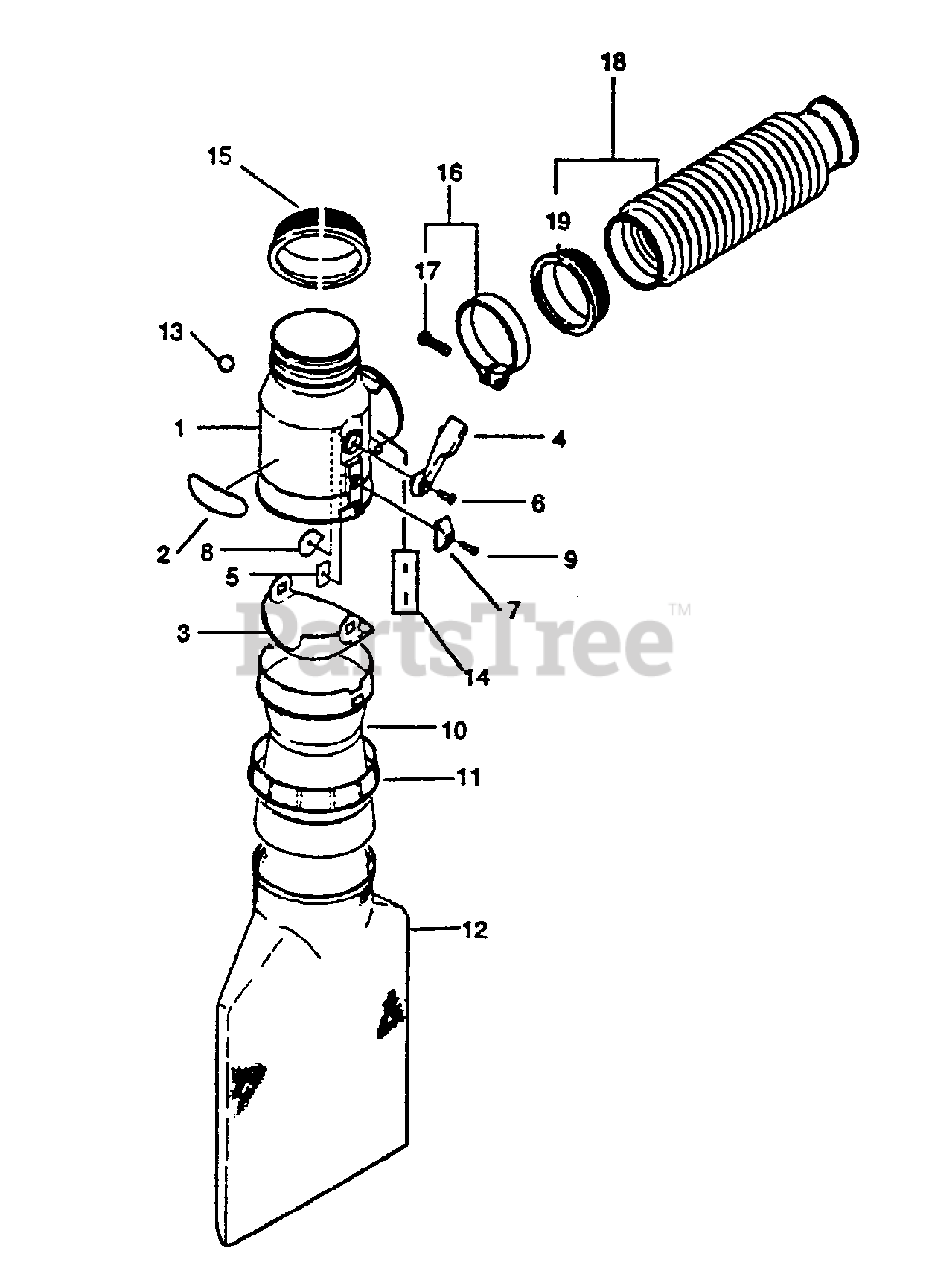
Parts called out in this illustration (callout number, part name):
1	TUBE, SUCTION
2	LABEL - ECHO
6	SCREW - 5X14
9	SCREW - 4X14
10	CONNECTOR
12	BAG, DEBRIS
13	RING, RETAINING - 8
14	LABEL - FUNCTION
15	COUPLER, SUCTION
16	CLAMP KIT
17	SCREW - 5X20
18	FLEXIBLE TUBE KIT
19	COLLAR
